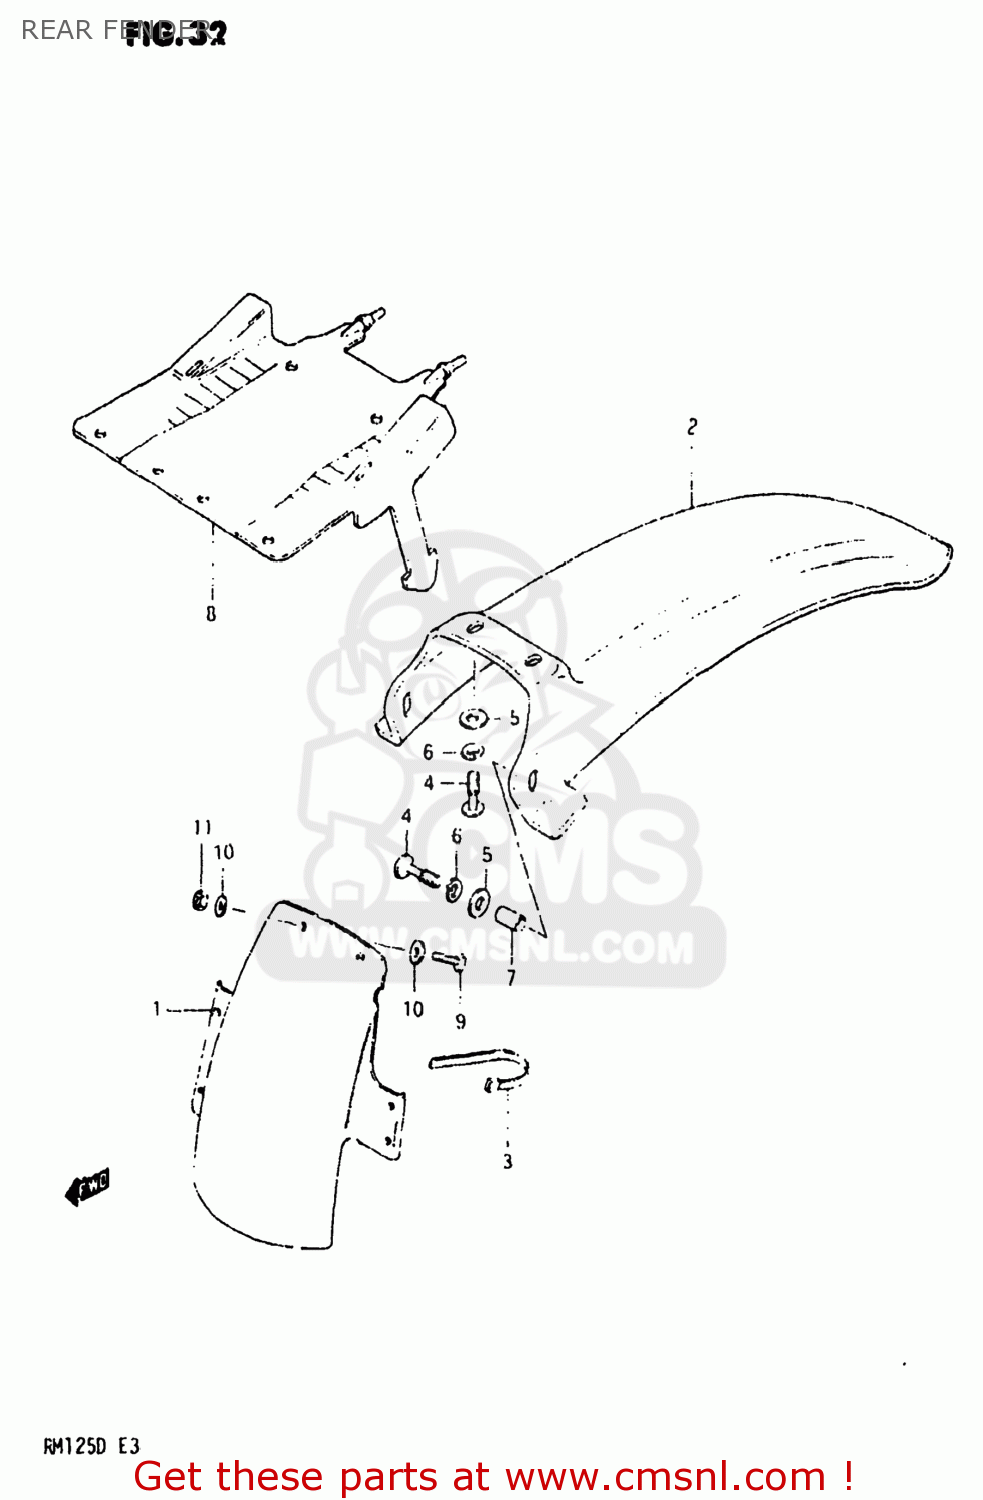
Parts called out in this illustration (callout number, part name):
1	REAR FENDER,FRONT
2	FENDER,REAR
3	CLAMP
4	SCREW
5	WASHER (6.5X20X1.2)
6	LOCK WASHER
7	SPACER
8	GUIDE,RR FENDER MUD
9	SCREW
10	WASHER
11	NUT
